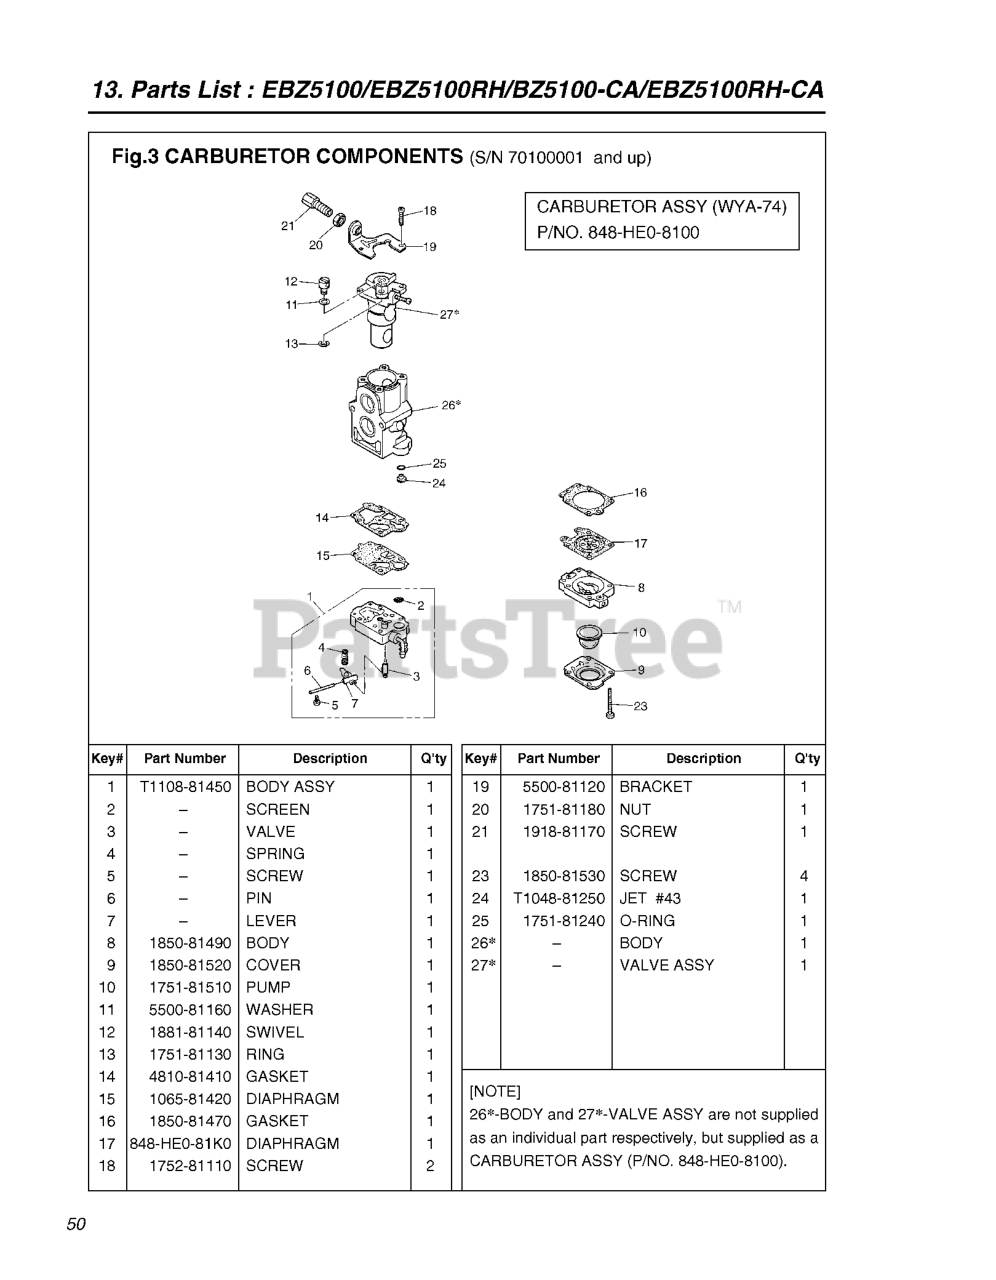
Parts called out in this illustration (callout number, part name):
1	BODY-A-PUMP
9	1OVER
11	WASHER
12	SWIVEL
13	RING
15	DIAPHRAGM
17	DIAPHRAGM
18	SCREW
19	BRACKET
20	NUT
21	ADJUSTER
26	CARBURETOR***
27	CARBURETOR***
